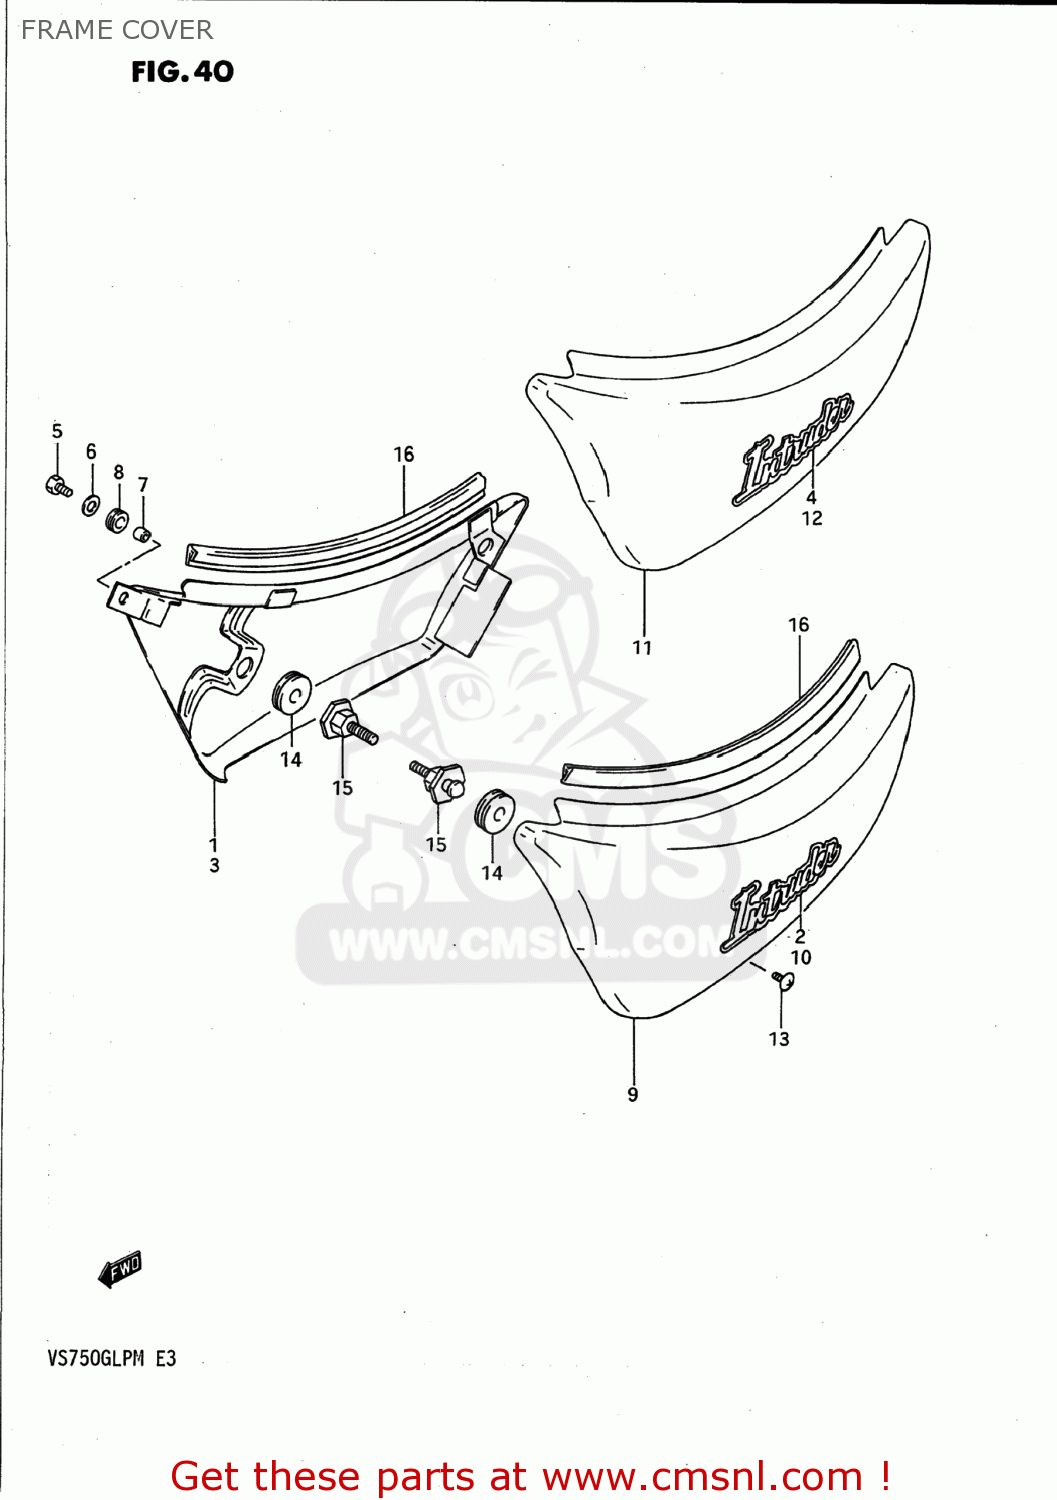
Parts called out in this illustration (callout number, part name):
1	COVER,FRAME,RIGHT
2	EMBLEM,FRAME COVER
3	COVER,FRAME,RIGHT
4	EMBLEM,FRAME COVER
5	BOLT
6	WASHER(6.5X18X1.6)
7	SPACER (6.1X8X5.2)
8	CUSHION
9	COVER,FRAME,LEFT
10	EMBLEM,FRAME COVER
11	COVER,FRAME,LEFT
12	EMBLEM,FRAME COVER
13	SCREW
14	CUSHION
15	BOSS,FRAME COVER
16	MOLDING, FRAME COVER
